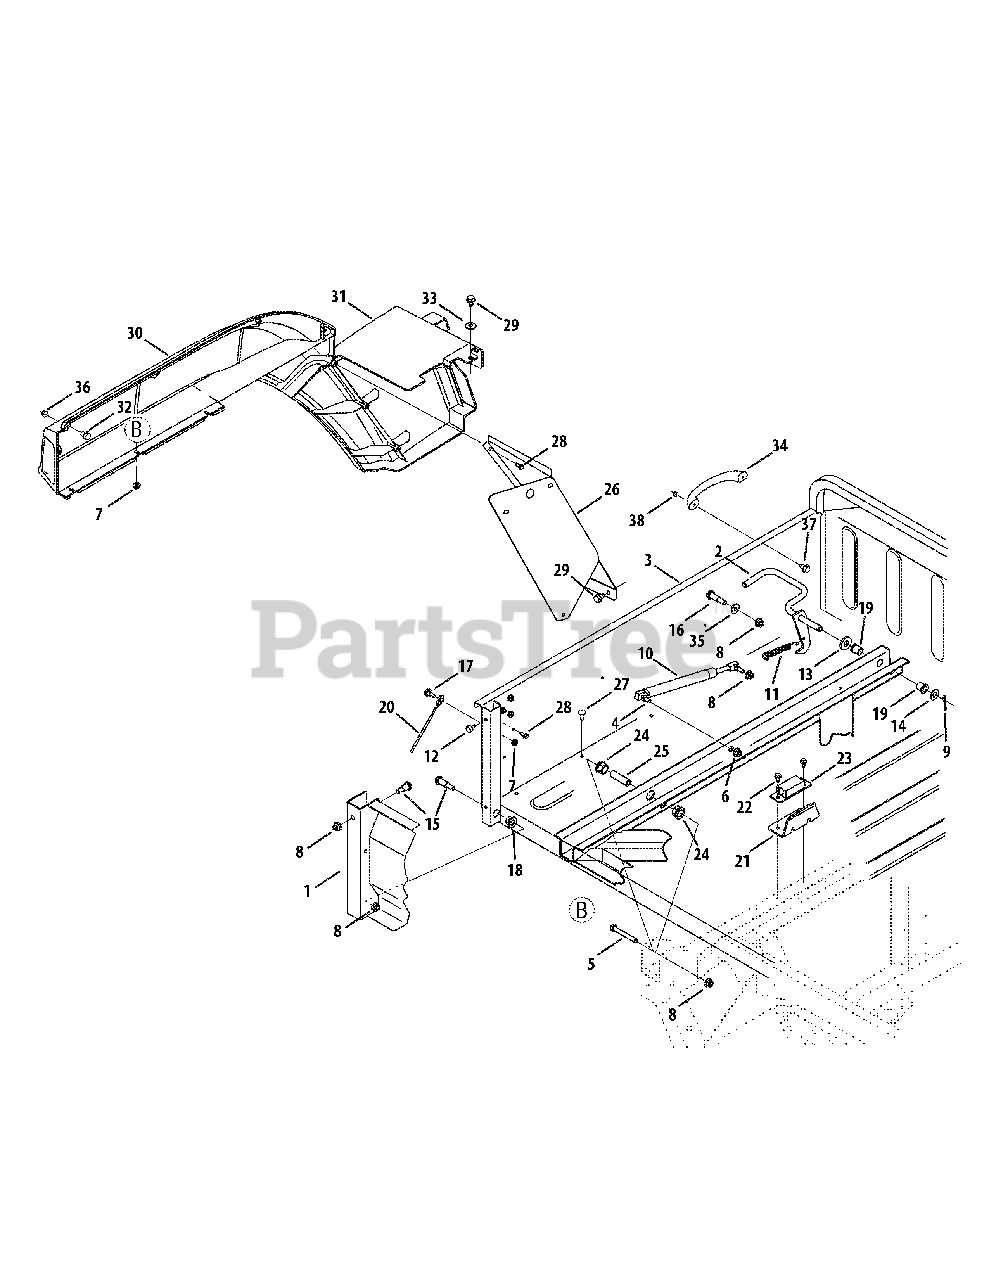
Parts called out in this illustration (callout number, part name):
1	Tail Gate Assembly - Black
1	Tail Gate Assembly - Cub Yellow
1	Tail Gate Assembly - Olive Green
1	Tail Gate Assembly - Red
2	Lvr Asm, bed, latch
3	Box Asm, bed - Black
3	Box Asm, bed - Yellow
3	Box Asm, bed - Red
3	Box Asm, bed - Green
4	Stud, ball, 5/16-18
5	Screw, 3/8-16, 2.75, gr5, std
6	Nut, flglk, 5/16-18, grf, nylon
7	Nut, flglk, 1/4-20, grf, nylon
8	Nut, flglk, 3/8-16, grf, nylon
9	Pin, cot, 5/32, 1.25
10	Spr, gas, 6.91 Stroke
11	Spr, extn, .50 Od X 4.35 Lg
12	Bumper, .62 Dia. x .3
13	Wash, flat, .531 X 1.25 X .181
14	Wash, flat, .510 X 1.00 X .060
15	Scr, shldr, .50 X .685, 3/8-16
16	Scr, shldr, .50x.925, 3/8-16
17	Scr, shldr, .375x.280, 1/4-20
18	Brg, flg, hex, .506 Id X .590 Lg
19	Brg, flg, .503 X .689 X .792
20	Cbl, lanyard
21	Brkt, Bed Guide
22	Scr, tt, 1/4-20x.625, hxindwsh
23	Bmpr, suspn, extn
24	Brg, hex Flng .629 Id
25	Spcr, .390 Id X.625 Od X2.03 Lg
26	Brkt, Lh, Shld
27	Scr, Crg, 1/4-20, .62, Gr2
28	Scr, #12-16, .50, Hxindwsh
29	Scr, Tt, 5/16-18, 0.500
30	Fender, Lh Rr
30	Fender, Lh Rr, Camo
31	Fender, Lwr Lh Rr
31	Fender, Lwr Lh Rr, Camo
32	Screw, Mach., 1/4-20 x .500
33	Washer, Bell, .340 x .872 x .060
35	Washer, Flat, .385 x .870 x .092
36	Nut, Acorn, 1/4-20
37	Screw, Mach., 1/4-20 x .750
38	Nut, Hexlk., 1/4-20
